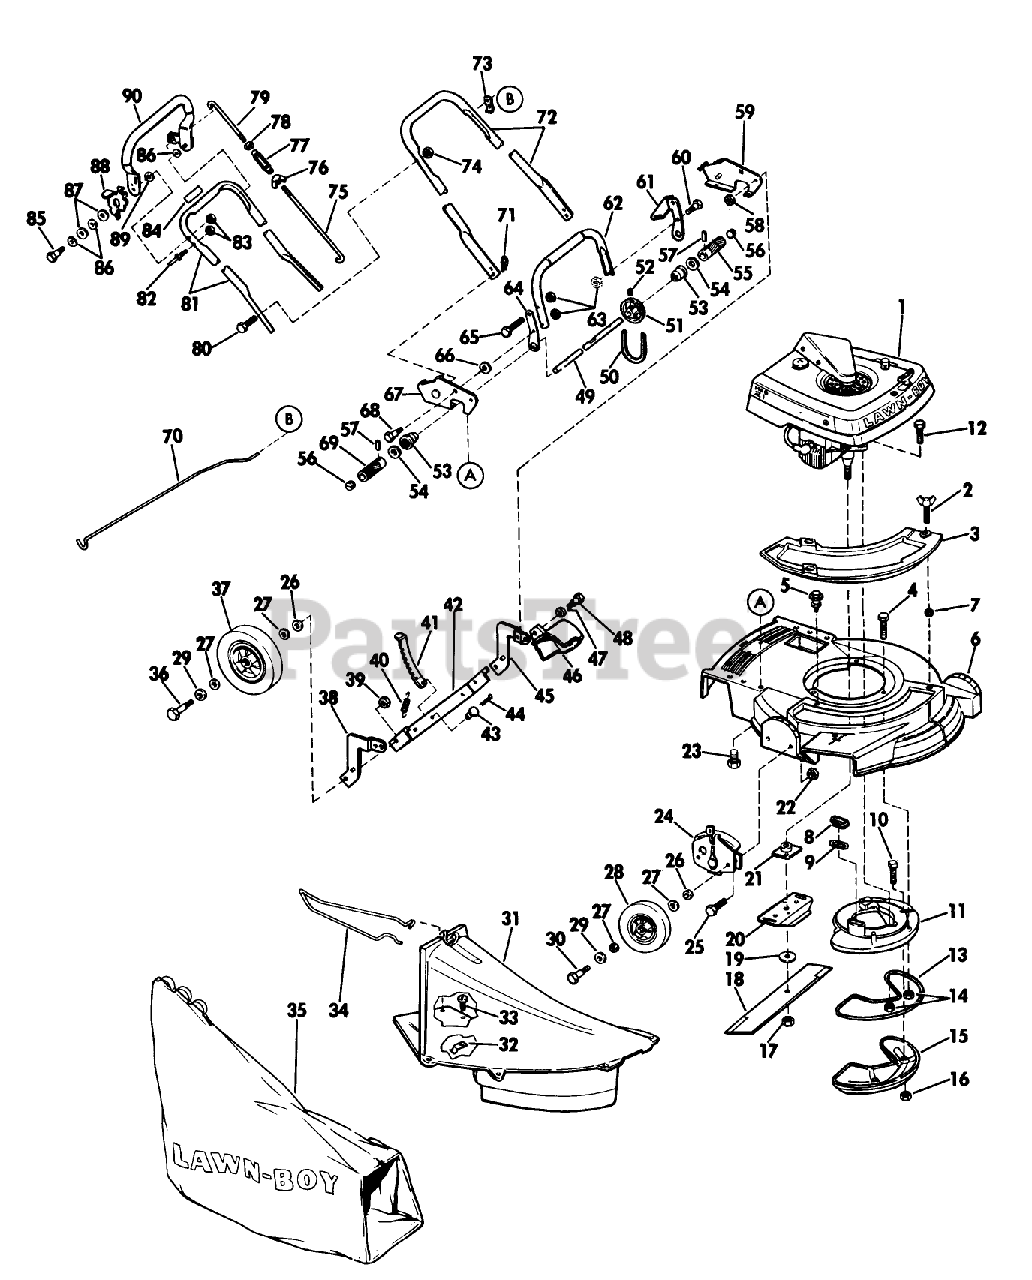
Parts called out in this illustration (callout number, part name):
2	WING SCREW LAWRE
9	GASKET S
16	LOCKNUT E
17	NUT-BLADE
21	PLATE AND COLLAR ASM
26	WASHER WROUGHT
30	BOLT WHEEL
39	LOCKNUT
40	SPRING N.A.S
47	Spring Washer
55	LEFT ROLLER
56	GREASE PLUG
68	BOLT PIONEER
70	GRASS BAG ROD-ARGO
71	HAIR PIN
85	BOLT PIONEER
86	WASHER M
